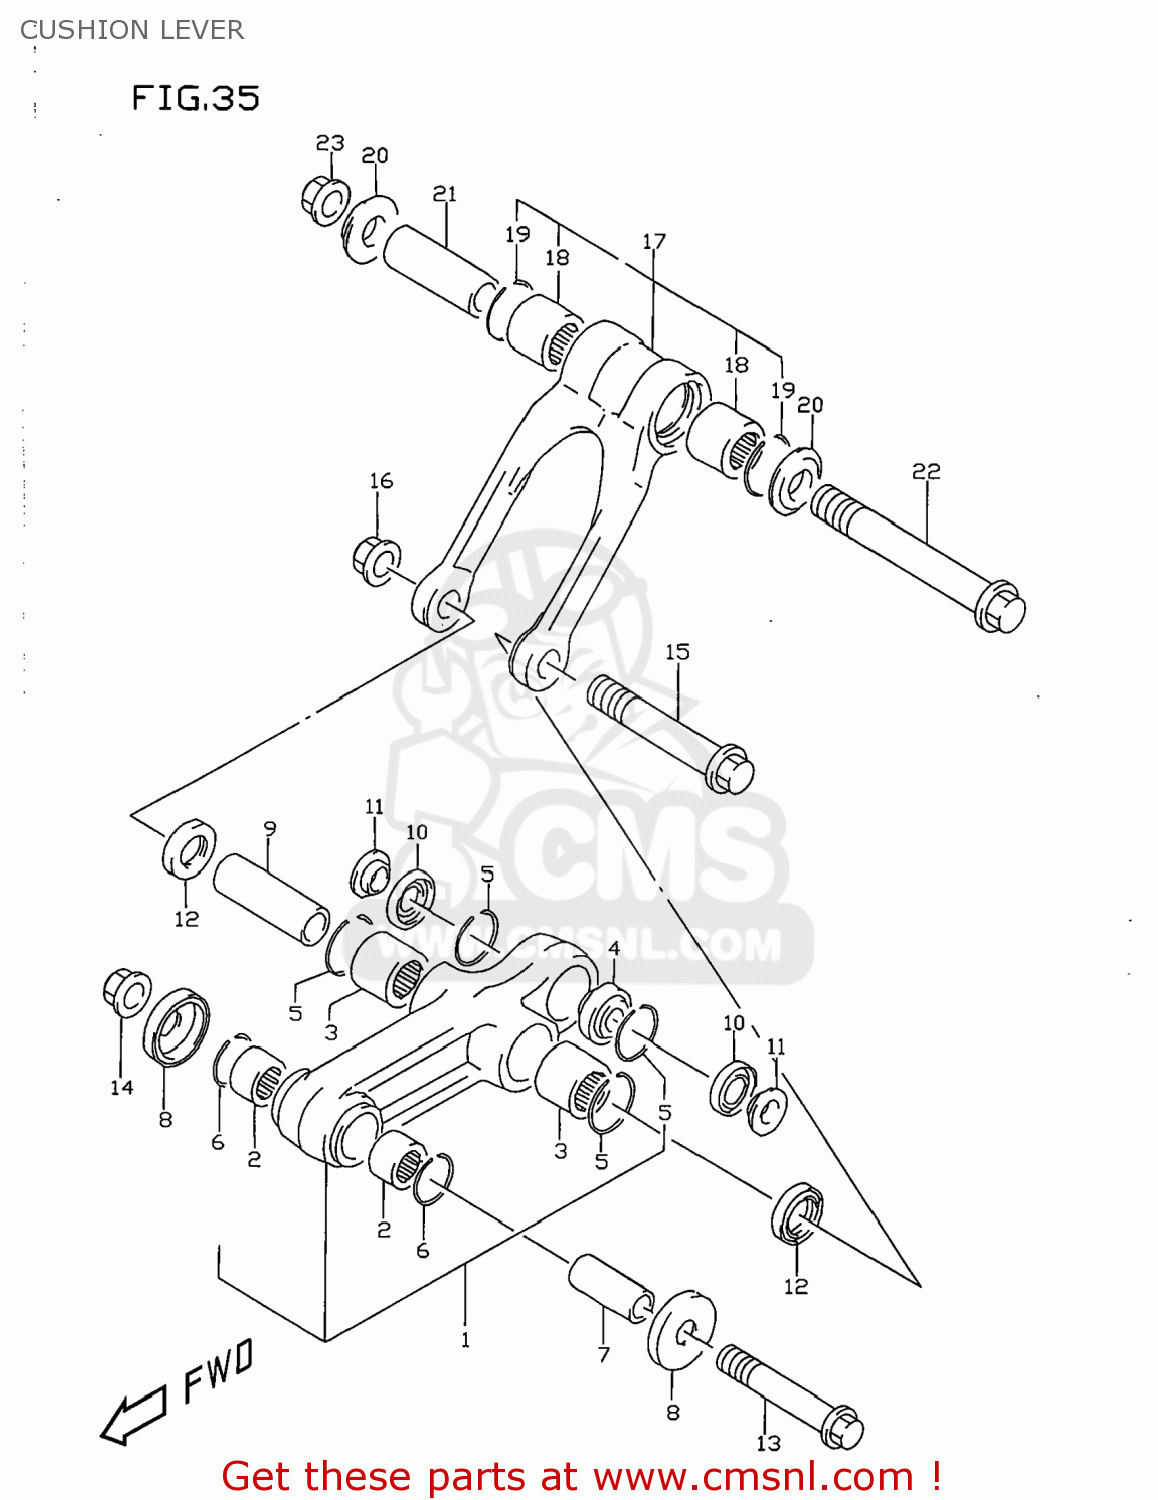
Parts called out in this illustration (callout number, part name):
1	LEVER SET,RR CUSHION
2	BEARING(14X20X12)
3	BEARING(17X24X20)
4	BEARING,RR CUSHION LEVER
5	RING,STOPPER
6	CIRCLIP,PISTON PIN
7	SPACER,RR CUSHION LEVER FR
8	SEAL,RR CUSHION LEVER FR DUST
9	SPACER,RR CUSHION LEVER CTR
10	SEAL,RR CUSHION LEVER RR DUST
11	SPACER,RR CUSHION LEVER RR
12	SEAL,OIL(17X24X3)
13	BOLT,RR CUSHION LEVER FR
14	NUT
15	BOLT,RR CUSHION LEVER CTR
16	NUT 12MM
17	ROD SET,REAR CUSHION,LEFT
18	BEARING(17X24X20)
19	RING,STOPPER
20	SPACER,RR CUSHION ROD SIDE
21	SPACER,RR CUSHION ROD
22	BOLT,RR CUSHION ROD
23	NUT 12MM
